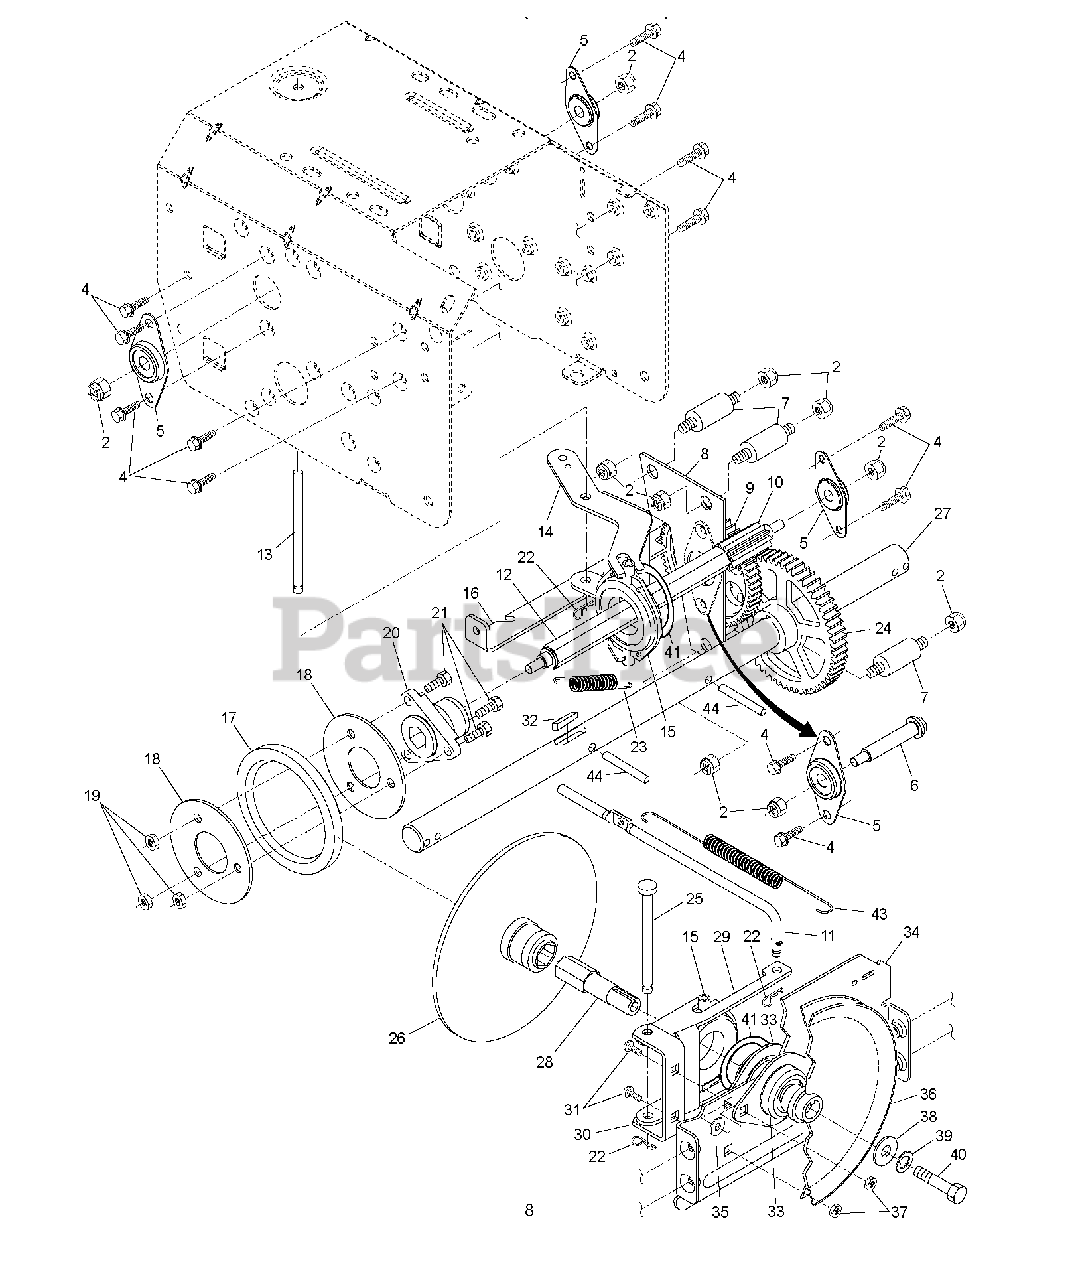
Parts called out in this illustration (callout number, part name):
2	NUT, LOCK 5/16-18
4	SCREW, HEX HEAD 5/16-18 X 1/2
5	BEARING, FLANGE
6	SHAFT, AUXILIARY
7	SPACER, PLATE
8	AUXILLARY PLATE
9	GEAR, INTERMEDIATE
10	GEAR, PINION
11	ROD.CLUTCH.YELLOW.ZINC
12	SHAFT.HEX.LONG
13	PIN, PIVOT
14	LEVER, SPEED CONTROL
15	TRUNNION BEARING ASSY
16	BRACKET, PIVOT, SHIFT
17	RING, RUBBER WHEEL
18	PLATE.RUBBER.WHEEL
19	NUT.CENTERLOCK.5/16-
20	HUB, RUBBER WHEEL
22	RETAINER CLIP PM
23	SPRING, BIAS
24	GEAR, AXLE (58T)
25	PIN, PIVOT LEVER
26	DRIVE PLATE WELDMENT
27	SHAFT.AXLE.16".SNOW
28	SHAFT.HEX.SHORT
29	LEVER.SHIFTER.PLATE.BLACK
30	BRACKET, SHIFTER SUPPORT
31	BOLT
32	KEY, SQUARE 1/4 X .875
33	BEARING FLANGE
34	PLATE.DRIVE.MOUNTING.BLACK
35	SPACER, BEARING
36	PULLEY.TRACTION.7.75
37	NUT, HEX FLANGE 5/16-18
38	WASHER, FLAT
39	LOCKWASHER
41	RETAINING RING
43	SPRING.RETURN
44	PIN.ROLL.3/16
